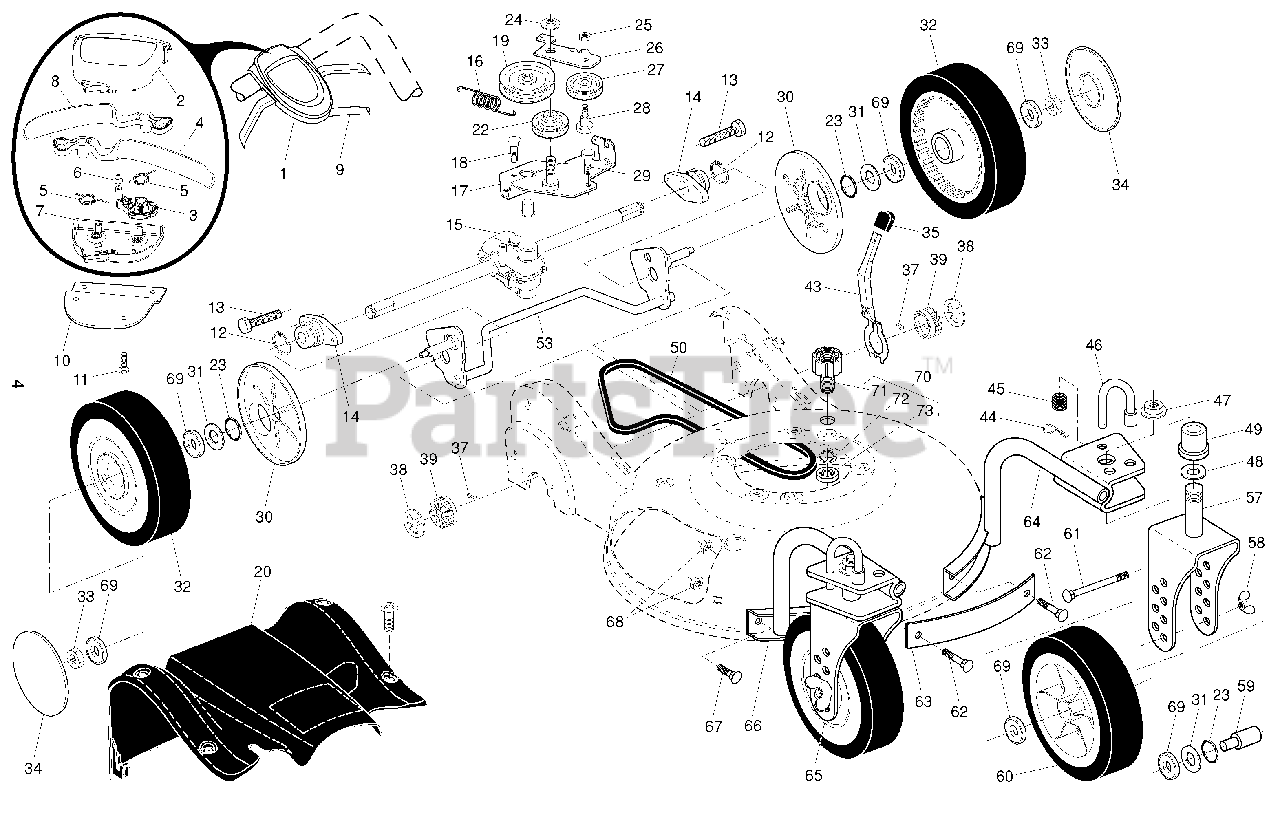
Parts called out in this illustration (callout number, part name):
1	Drive Control Assembly
2	Cover, Drive Control, Top
3	Cam, Drive Control
4	Lever, Drive Control, LH
6	Bushing, Drive Control
7	Cover, Drive Control, Bottom
8	Lever, Drive Control, RH
9	Cable, Drive Control
10	Bracket, Mounting, Drive Control
11	Screw, Torx Head #8 x 5/8
12	Ring, Retaining
14	Bearing / Axle Support
15	Gear Case Assembly, Complete
16	Spring, Return
17	Belt Keeper
19	Pulley, Drive
20	Drive Cover Assembly
22	Pulley Assembly, V-Groove
23	O-Ring
24	Nut, Hex, Flangelock
25	Nut, Hex, Lock
27	Pulley, Idler
28	Bolt, Hex Head, Shoulder
29	Screw 1/4-20 x 1/16
30	Cover, Dust, Wheel
31	Washer, Flat 3/8
32	Wheel Assembly, Rear 9 x 2-1/4
33	Nut, Hex
35	Knob, Star
43	Lever, Selector, Wheel Height, Rear
44	Clip, Retainer
47	Nut, Hex, Flangelock
48	Washer, Flat 1/2
50	Belt, Drive
53	Rear Axle Assembly
57	Bracket, Caster Wheel, LH
58	Wing Nut 5/16-18
60	Wheel Assembly, Front 9 x 2-1/4
61	Bolt, Carriage 5/16-18 x 3-1/2
62	Bolt, Carriage 5/16-18 x 7/8
63	Strap, Front
64	Support Tube Assembly, LH
65	Bracket, Caster Wheel, RH
66	Support Tube Assembly, RH
67	Bolt, Carriage 5/16-18 x 5/8
68	Nut, Hex 5/16
69	Bearing, Ball (Wheel)
70	Water Washout Assembly
71	Fitting, Hose, Water Washout
72	Washer, Lock, Internal Tooth
73	Locknut, Hex, with O-Ring
